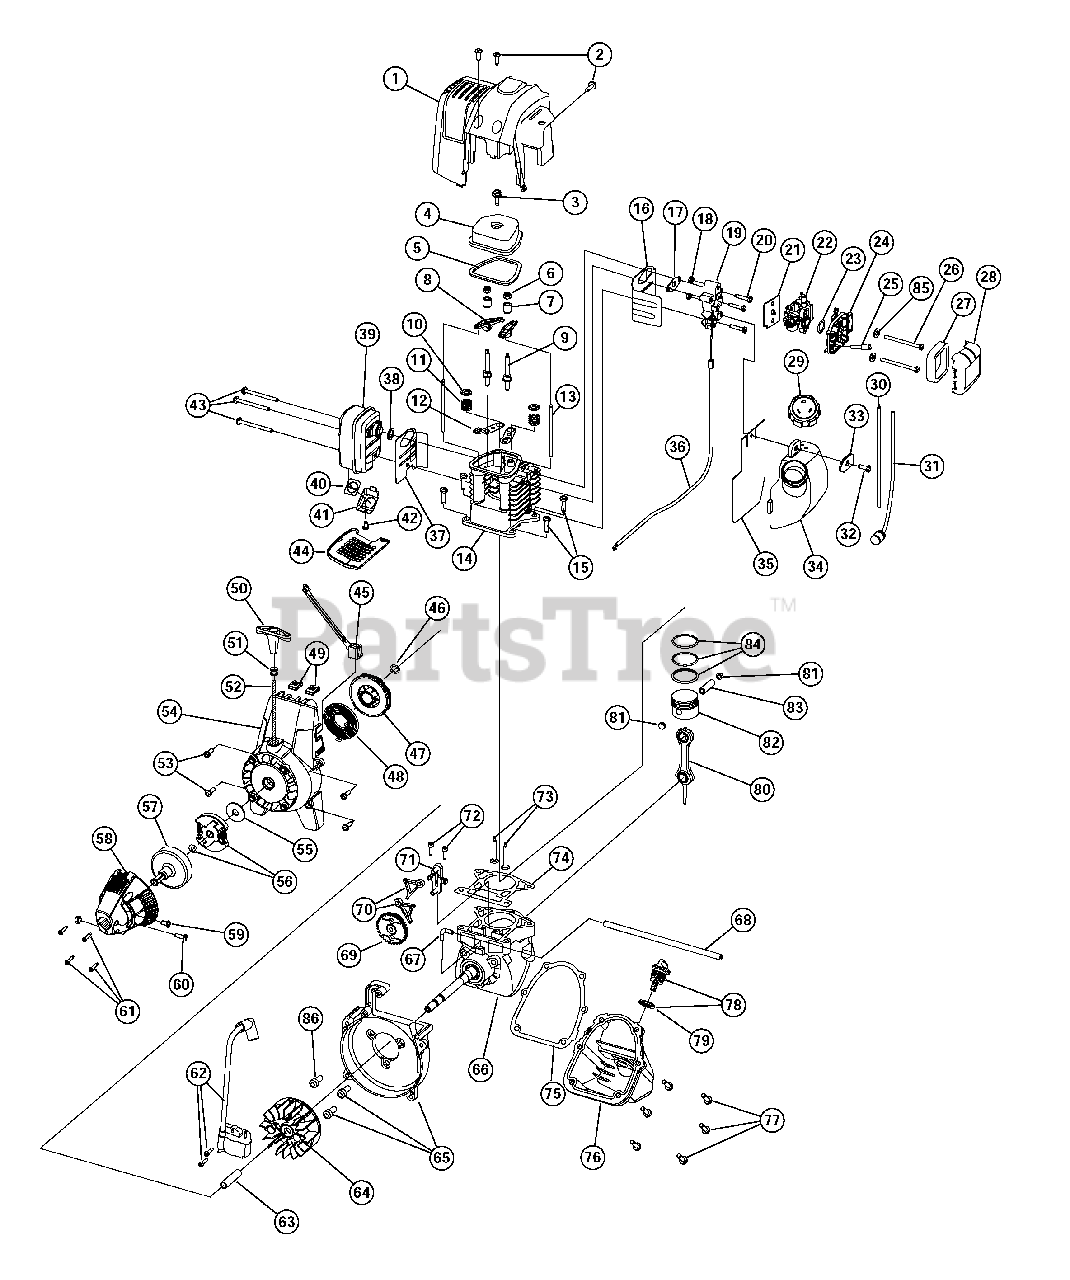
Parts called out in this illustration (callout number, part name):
1	Engine Cover
2	Engine Cover Screws
3	Valve Cover Screw
4	Valve Cover
5	Valve Cover Gasket
6	Rocker Adjustment Nut
7	Rocker Arm Pivot
8	Rocker Arm
9	Rocker Arm Stud
10	Valve Spring Retainer
11	Valve Spring
12	Push Rod Guide
13	Push Rod
14	Cylinder Head
15	Cylinder Screw
16	Intake Baffle
17	Carburetor Mount Gasket
18	Nut
19	Carburetor Mount
20	Carburetor Mount Screw
21	Carburetor Gasket
22	Carburetor with Primer
23	O-Ring, Carburetor
24	Air Filter Assembly
25	Breather Tube
26	Air Filter Mounting Screw
27	Air Filter
28	Air Filter Cover
29	Fuel Cap
30	Fuel Return Line
31	Fuel Pick-Up Line with Filter
34	Fuel Tank Assembly
35	Fuel Tank Shield
36	Throttle Cable
37	Muffler Baffle
38	Muffler Gasket
39	Muffler
40	Spark Arrestor Screen
41	Screen Cover
43	Muffler Mounting Screw
44	Muffler Cover
45	Switch with Wires
46	Pulley Retainer
47	Recoil Pulley
48	Recoil Spring
49	Nut Clip
50	Pull Handle
51	Rope Guide
53	Starter Housing Screw
54	Starter Housing Assembly
55	Clutch Washer
56	Clutch with Spacer
57	Clutch Drum
58	Clutch Cover
59	Anti-Rotation Screw
60	Screw
61	Clutch Cover Screw
62	Ignition Module with Screws
64	Flywheel
65	Shroud Assembly w\Screws
66	Crankcase Assembly
67	90° Elbow
68	Breather Hose
69	Cam Gear
70	Cam Follower
71	Cam Bracket
72	Cam Bracket Screw
73	Valves, Intake and Exhaust
74	Cylinder Gasket
75	Oil Pan Gasket
76	Oil Pan
77	Oil Pan Screw
78	Dipstick Assembly
80	Connecting Rod
81	Wrist Pin Button
82	Piston
83	Wrist Pin
84	Piston Ring Set
